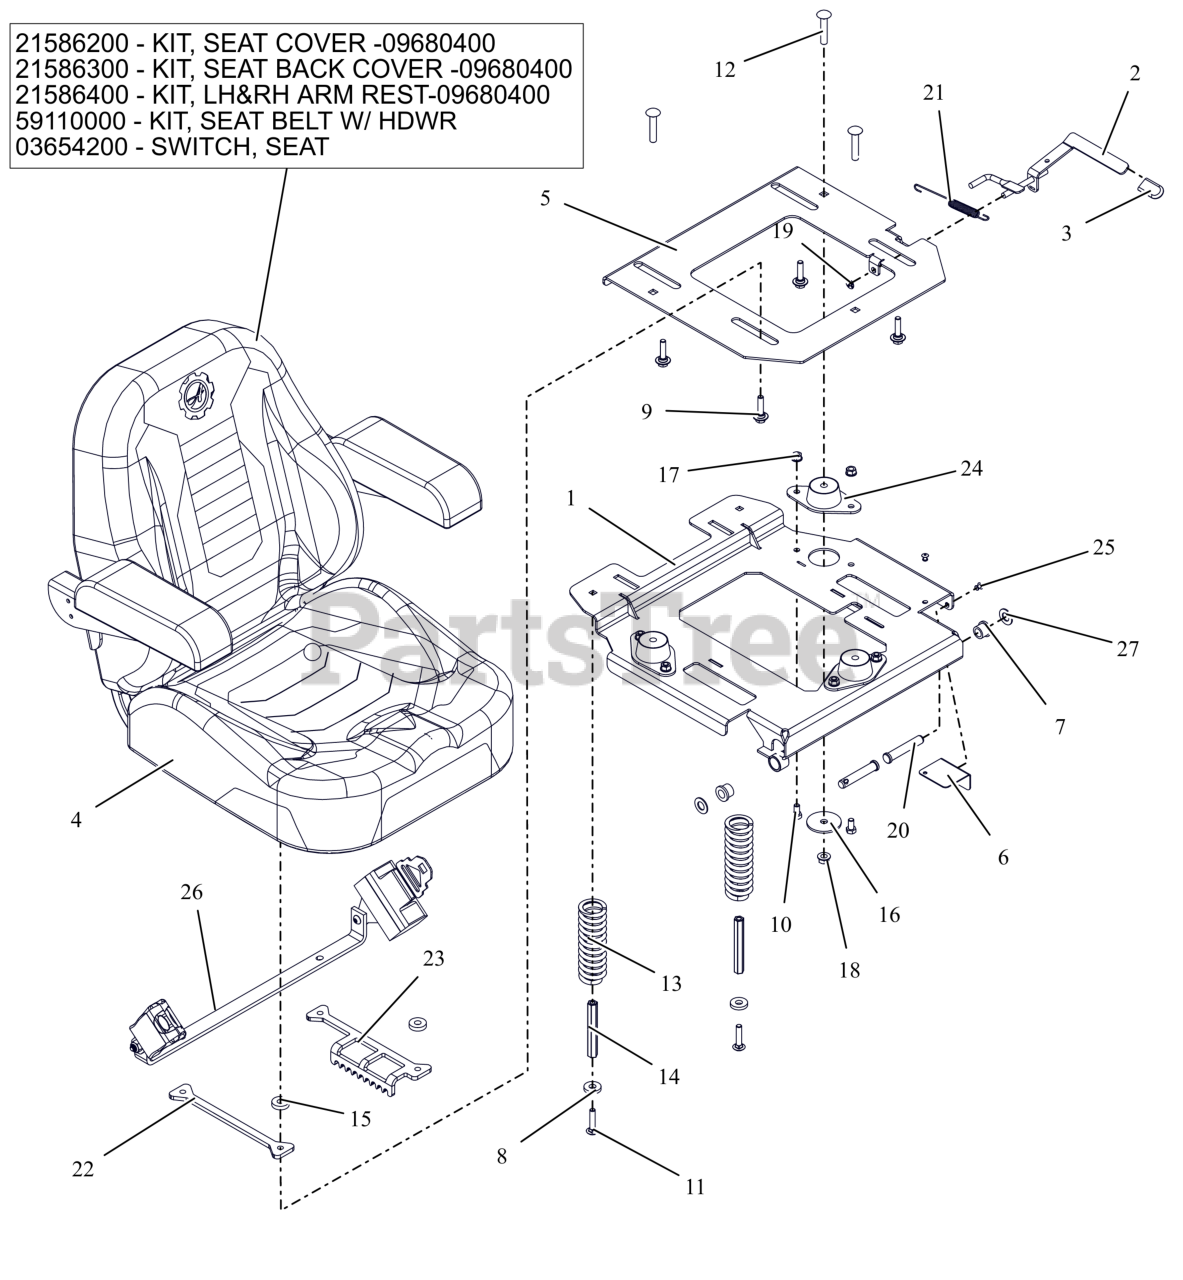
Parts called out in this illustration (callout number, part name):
1	WLDMT- ISO MTG PLATE 3PT
2	WLDMT, SEAT SLIDE LEVER
3	GRIP, SEAT LEVER, GREY
4	SEAT- APEX/ZENITH
4	KIT, SEAT COVER BOTTOM
4	KIT, SEAT BACK COVER
4	KIT, LH & RH ARM REST
4	KIT-SEAT BELT REPLACE-05007300
4	SWITCH- SEAT
5	PLATE- SEAT MTG 3PT (ISO KIT)
6	GUARD, SEAT FAN (SH)(BLACK)
7	BSHG, FLG .516X.750X.625X.937
8	WSHR, FLT .406X1.00X.188 ZCC
9	BOLT SHLDR .31-18 X .175
10	BLT, HEX .31-18X.625 G5 ZCC
11	BLT,RHSN .31-18X1.50 G5 ZCC
12	BLT,RHSSN.375-16X2.00 G5 ZCC
13	SPRING, COMPRESSION SEAT 224LB
14	NUT, COUPLING 5/16X18 X 3.75
15	WSHR, FLT .390X1.00X.250 ZCC
16	WSHR-FL-STL 0.406X2X0.125 ZCC
17	NUT,LK-CTR-FLG .31-18 GF ZCC
18	NUT-LK-CTR-FLG .375-16 GF ZCC
19	NUT-PUSH .312
20	PIN-CLIC .50X2.70X2.31 -ZCC
21	SG-TENS .06X.482X5.35
22	PLATE, ADJ SEAT SLIDE (BLACK)
23	PLATE, SEAT ADJ (BLACK)
24	MOUNT, FAIL-SAFE COMPRESSION
25	RIVET, .1875 AL/AL .126-.250
26	KIT-SEAT BELT REPLACE-05007300
27	WSHR, FLT .531X1.00X.063 ZCC
